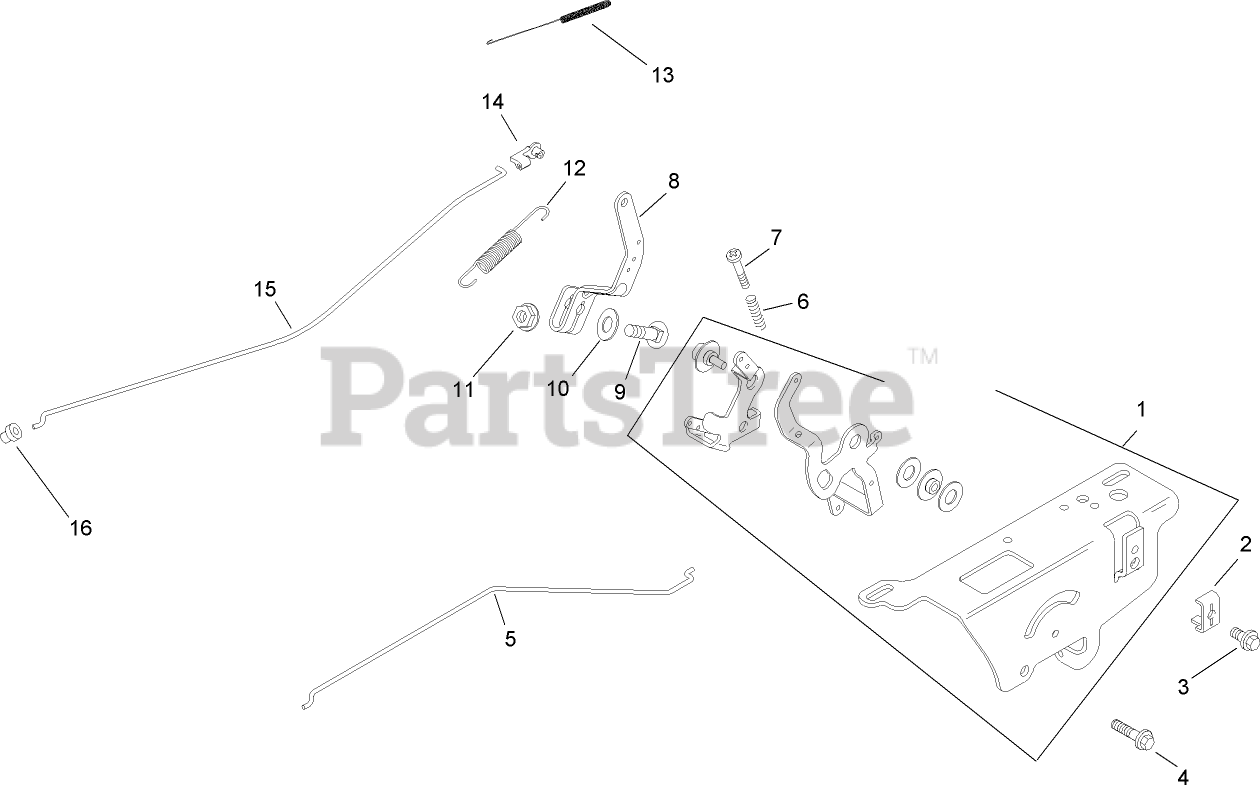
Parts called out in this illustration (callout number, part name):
1	Speed Control ASM
2	CLAMP-CABLE
3	SCREW-FLANGE, THREAD FORMING (M5X0.8X16)
4	Screw-Socket, 6 Lobed (Thread Forming, M6x1.0x20)
5	Linkage-Choke (Single Wire)
6	Spring-Control, Speed
7	Screw-Thread Forming (M4x0.7x25)
8	Lever-Governor
9	Bolt-Square Neck, Round Head (1/4-20x1)
10	Washer-Lock, Internal Tooth (1/4)
11	Nut-Flange, Hex (1/4-20)
12	Spring-Governor
13	Spring-Linkage
14	BUSHING-RETAINING, LINKAGE
15	Linkage-Throttle
16	BUSHING-LINKAGE, THROTTLE
